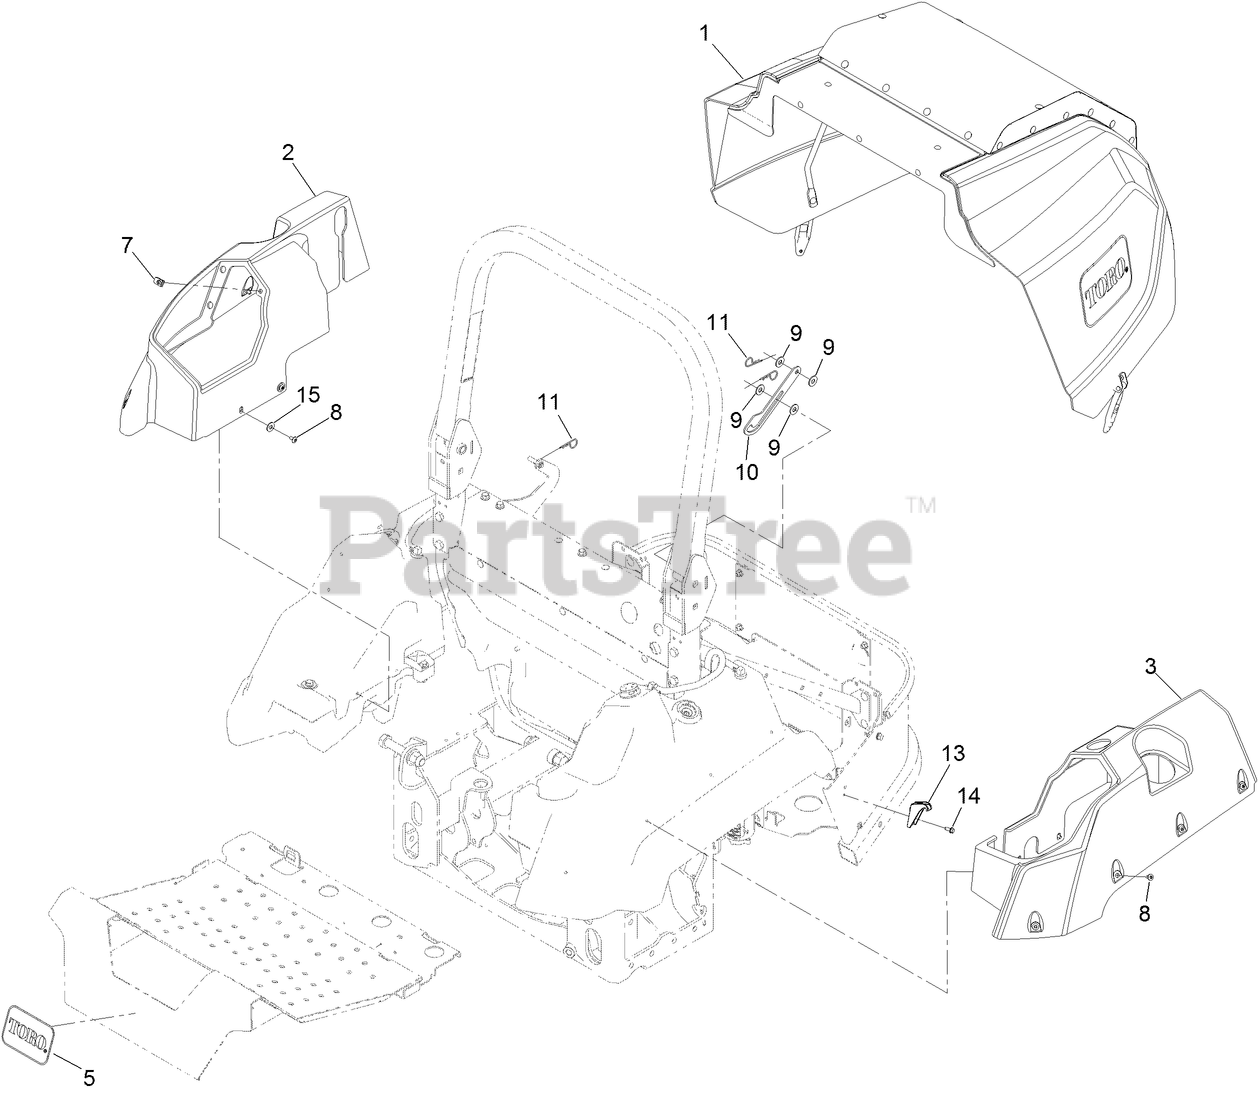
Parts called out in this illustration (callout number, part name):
1	HOOD ASM
2	COVER-TANK, RH
3	COVER-TANK, LH
5	DECAL
8	SCREW-TORX
9	WASHER-FLAT
10	PROP-HOOD
11	PIN-COTTER, HAIR
13	LATCH-CATCH
14	SCREW-HWH
15	WASHER-FLAT
